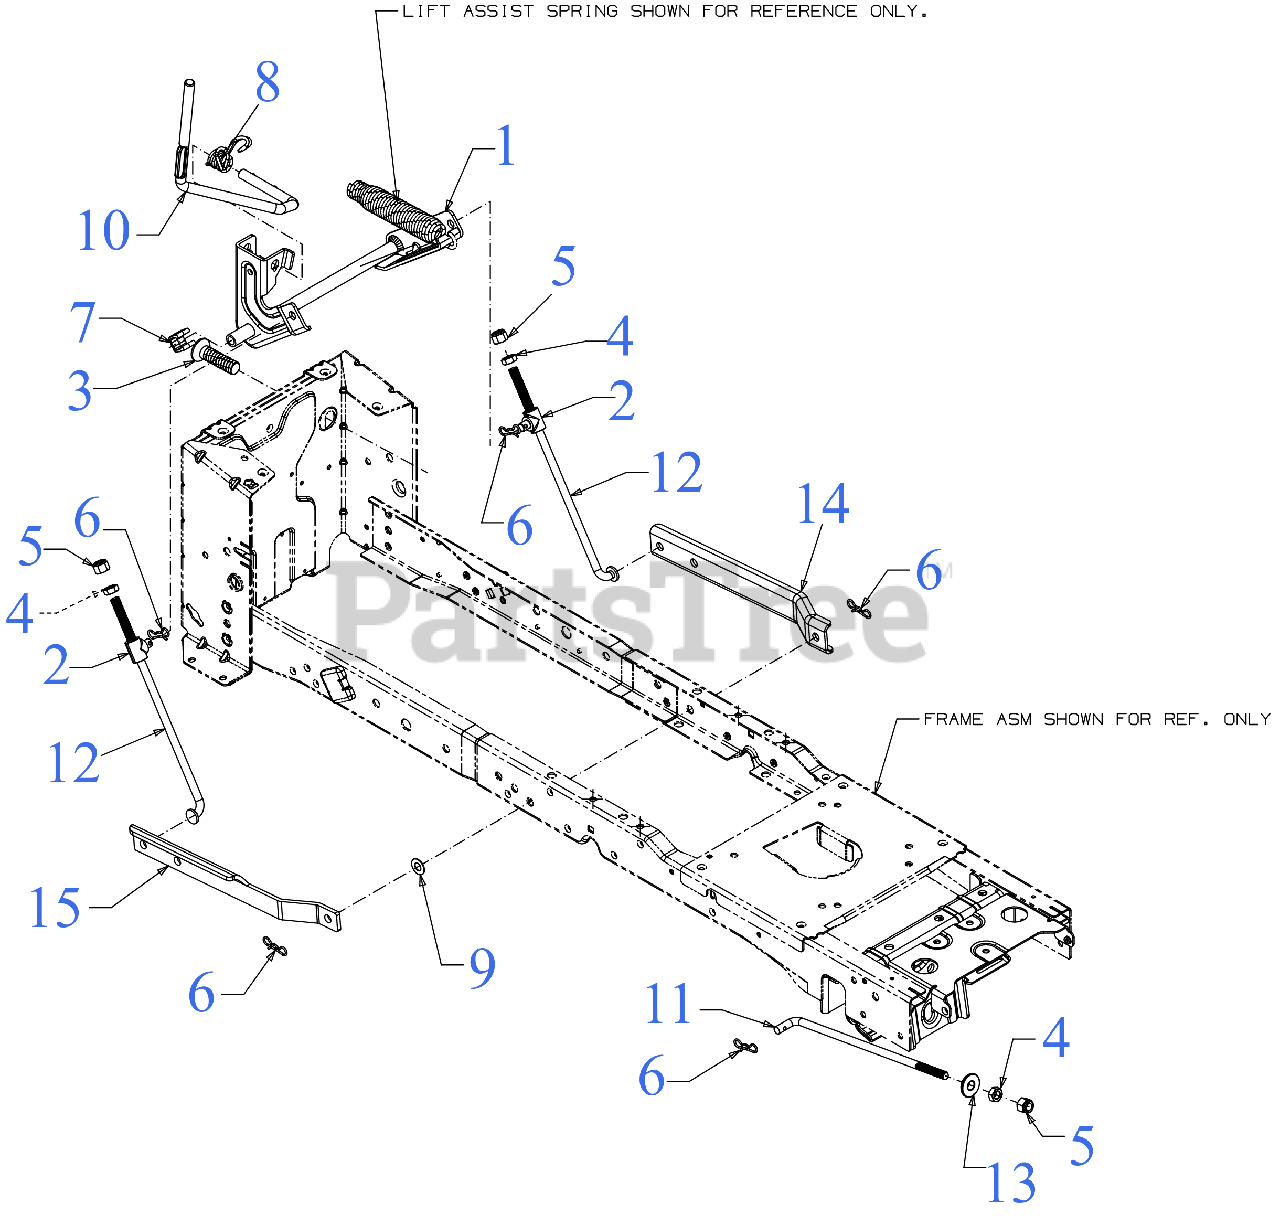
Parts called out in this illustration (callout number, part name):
1	LIFT SHAFT ASSEMBLY
2	LIFT ROD FERRULE
3	LIFT SPRING INSERT
4	HEX JAM NUT 1/2-13
5	HEX LOCK NUT NYLON
6	BOW TIE COTTER PIN
7	SPACER-LIFT SHAFT
8	TORSION SPRING
9	FLAT WASHER .508X1.000X.040
10	DECK LIFT HANDLE
11	DECK FRONT LIFT ROD
12	ADJUSTMENT LIFT ROD
13	DECK LIFT PIVOT CUP
15	LIFT ARM (REAR)
